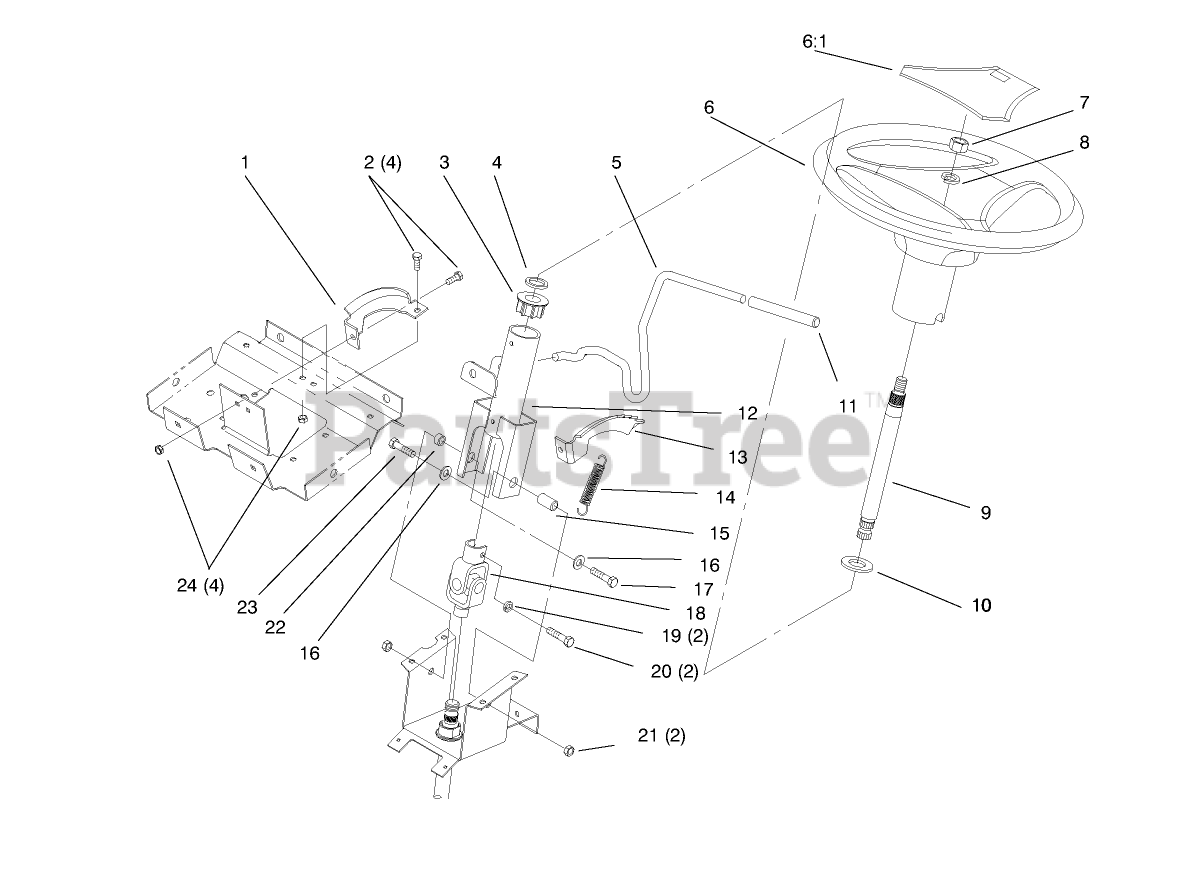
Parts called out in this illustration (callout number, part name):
1	BRACKET-SUPPORT, COLUMN
2	SCREW-HH
3	BUSHING-STEERING, UPPER
4	WASHER-BOWED
5	LEVER-TILT
6:1	COVER-WHEEL
7	NUT-HH
8	WASHER-LOCK
9	SHAFT-SHORT, STEERING
10	WASHER-FLAT
11	CAP-ROD, TILT
12	COLUMN ASM
13	BRACKET-DETENT
14	SPRING-EXTENSION
15	SPACER-YOKE
16	WASHER-PLAIN
17	SCREW-HH
18	U-JOINT, STEERING
19	WASHER-LOCK
21	NUT-LOCK, NI
22	SPACER-YOKE, RIGHT
23	SCREW-HH
24	NUT-HEX
